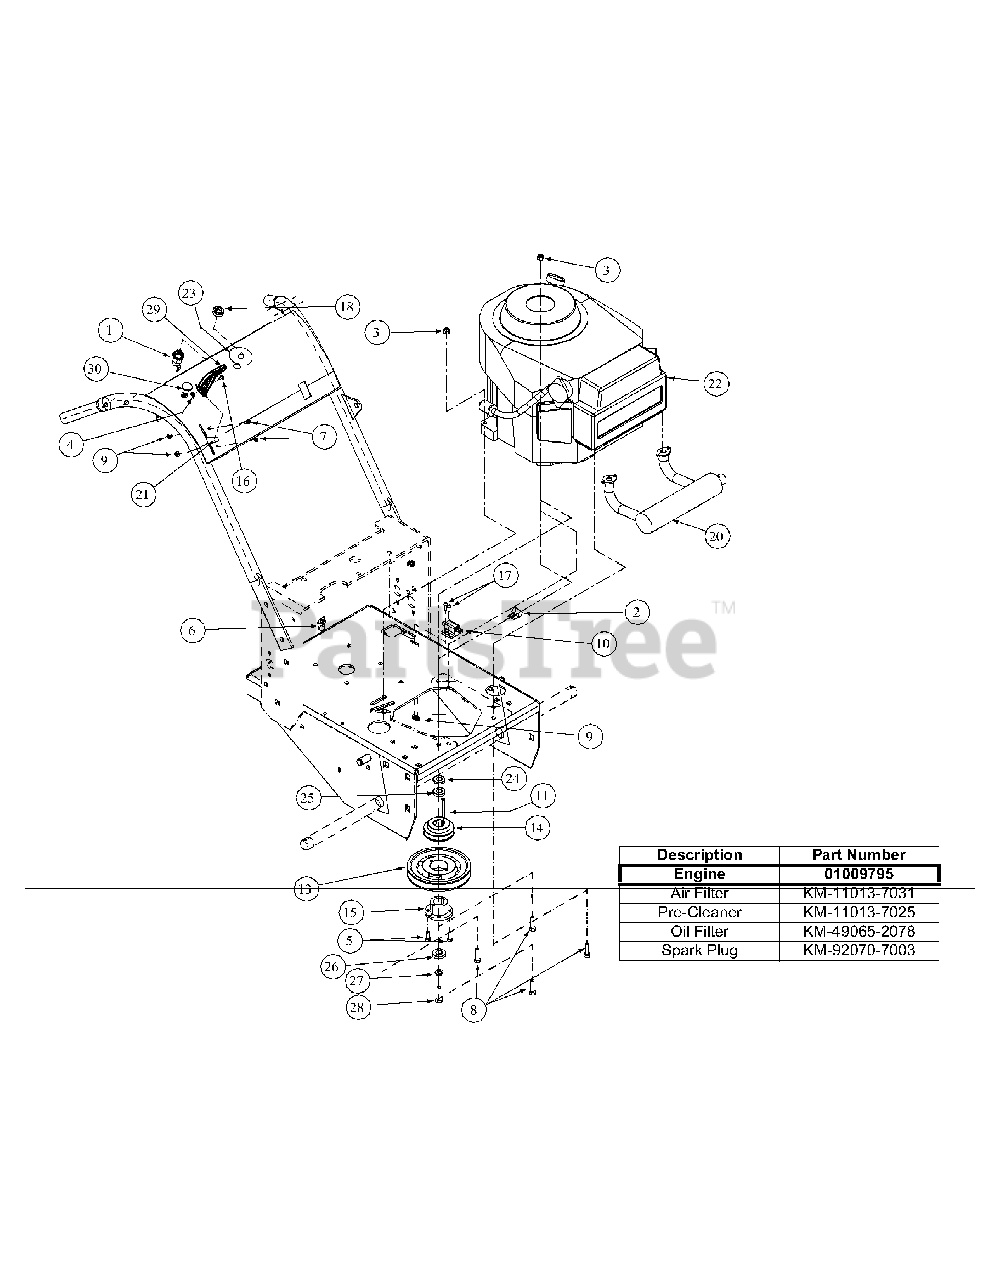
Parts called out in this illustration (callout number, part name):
1	Single Ignition ON/OFF Switch
1	Ignition ON/OFF Switch
2	Support Clamp
3	Nut, 5/16-18 Nylock
4	Nut, 8-32, w/ star washer
5	Hex Cap Screw, 1/4-20, .75
6	Support Clamp
7	Screw, Hex Washer, 10-32 x 1/2
8	Cap Screw, 5/16-18 x 2
9	Lock Nut, Nylon Insert, 10-32
10	Delta Switch
11	Key Stock, 1/4 x 1/4 x 2-3/4
12	Harness Wire
13	Deck Pulley
14	Traction Drive Pulley
15	Bushing Type D
16	Machine Screw, 8-32
17	Machine Screw, 10-32 x 5/8
18	Nut, w/Cap, 5/8-32, Ignition
19	Belt Transmission Drive
21	Throttle Control, w/Detent, 47.25
22	Engine, 15HP Kawasaki Kai
23	Decal, Pull Start Overlay
24	Engine Pulley Spacer, 12.5 Vanguard
25	Flat Washer
26	Clutch Washer
27	Lock Washer, 7/16
28	Capscrew, M10 x 1.5
29	Throttle Control Knob
30	Choke Cable
